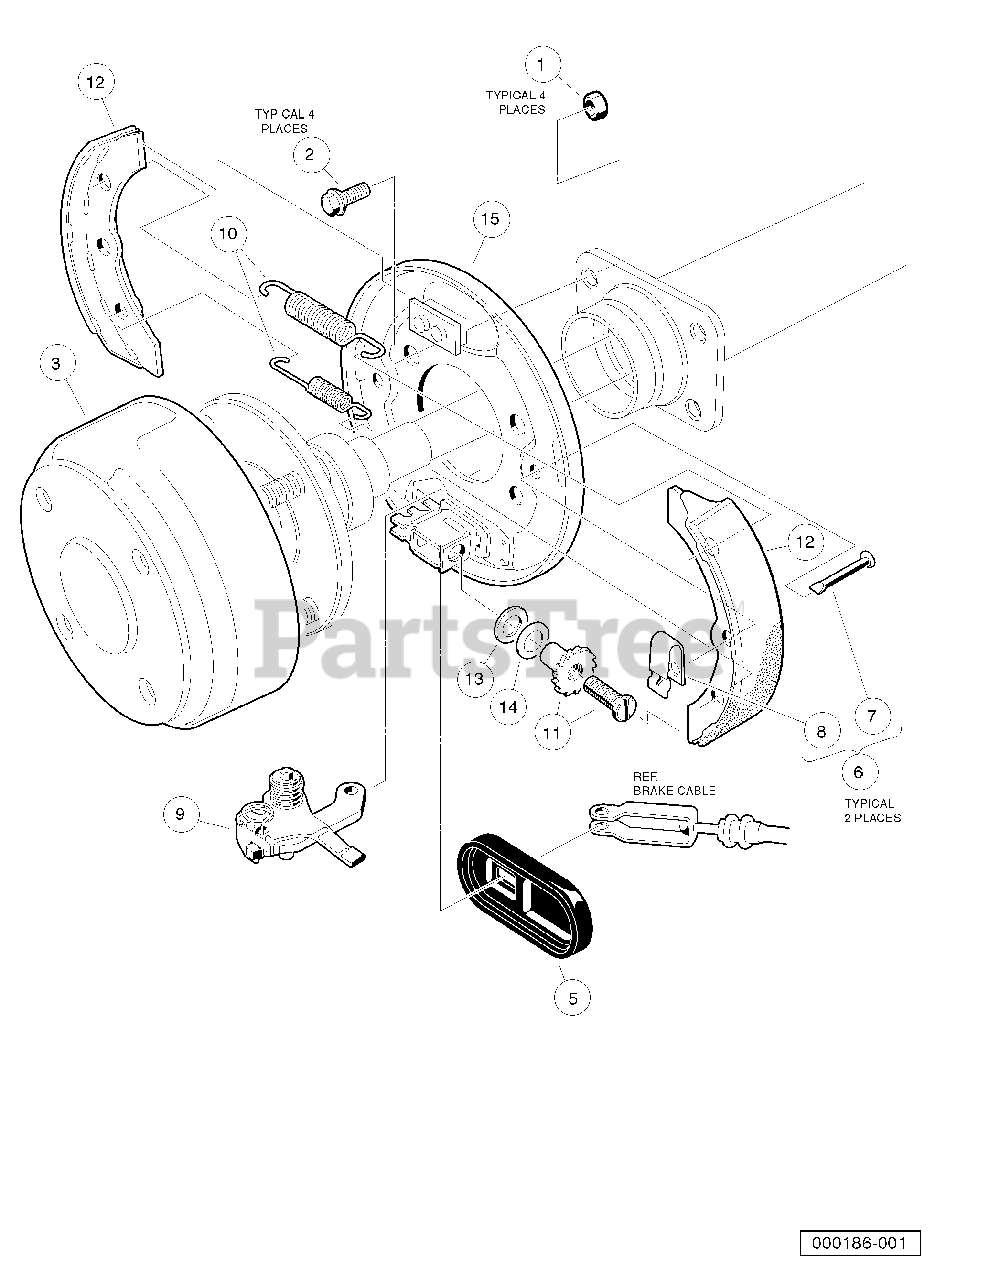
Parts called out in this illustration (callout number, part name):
1	Nut, 5/16-24 Hex Head Cone
2	Bolt, Brake Cluster Mounting
3	Drum without Center Hole, Brake
4	Cluster Assembly, Right (Passenger) Brake
5	Dust Cover
6	Kit, Shoe Retainer
7	Pin
8	Shoe Clamp Spring
9	Lever Assembly, Self-Adjusting Brake, Right
10	Package, Brake Spring, Self-Adjusting
11	Adj Mechanism, S.A. Brakes, Right
12	Package, Brake Shoe, Self-Adjusting
13	Plate, Washer, Brake, Self-Adjusting
14	Washer, Brake, Self-Adjusting
15	Plate Assembly, Right Brake Backing
16	Cluster Assembly, Left Brake
17	Dust Cover
18	Kit, Shoe Retainer
19	Pin
20	Shoe Clamp Spring
21	Lever Assembly, Self-Adjusting Brake, Left
22	Package, Brake Spring, Self-Adjusting
23	Adjusting Mechanism, Self-Adjusting Brake, Left
24	Package, Brake Shoe, Self-Adjusting
25	Plate, Washer, Brake, Self-Adjusting
26	Washer, Brake, Self-Adjusting
27	Plate Assembly, Left Brake Backing
